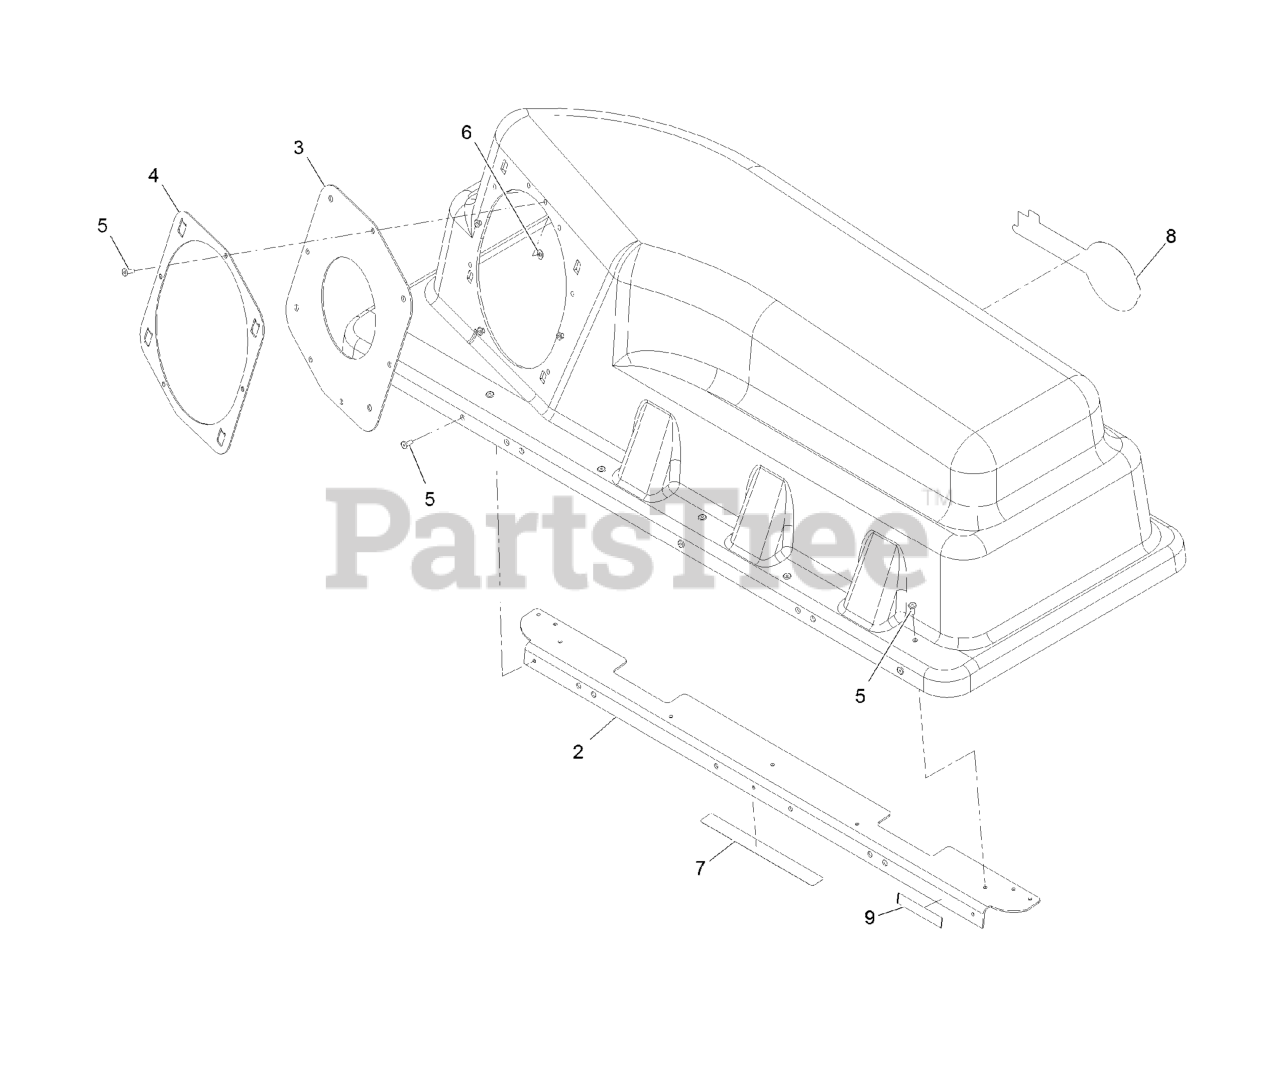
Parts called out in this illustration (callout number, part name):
2	STIFFENER-BAGGER, TOP
4	RING-RETAINER
5	RIVET-BLIND
6	WASHER-FLAT
7	DECAL-CRUSH HAZARD BAGGER
8	DECAL-EXMARK LOGO
9	DECAL-WARNING
